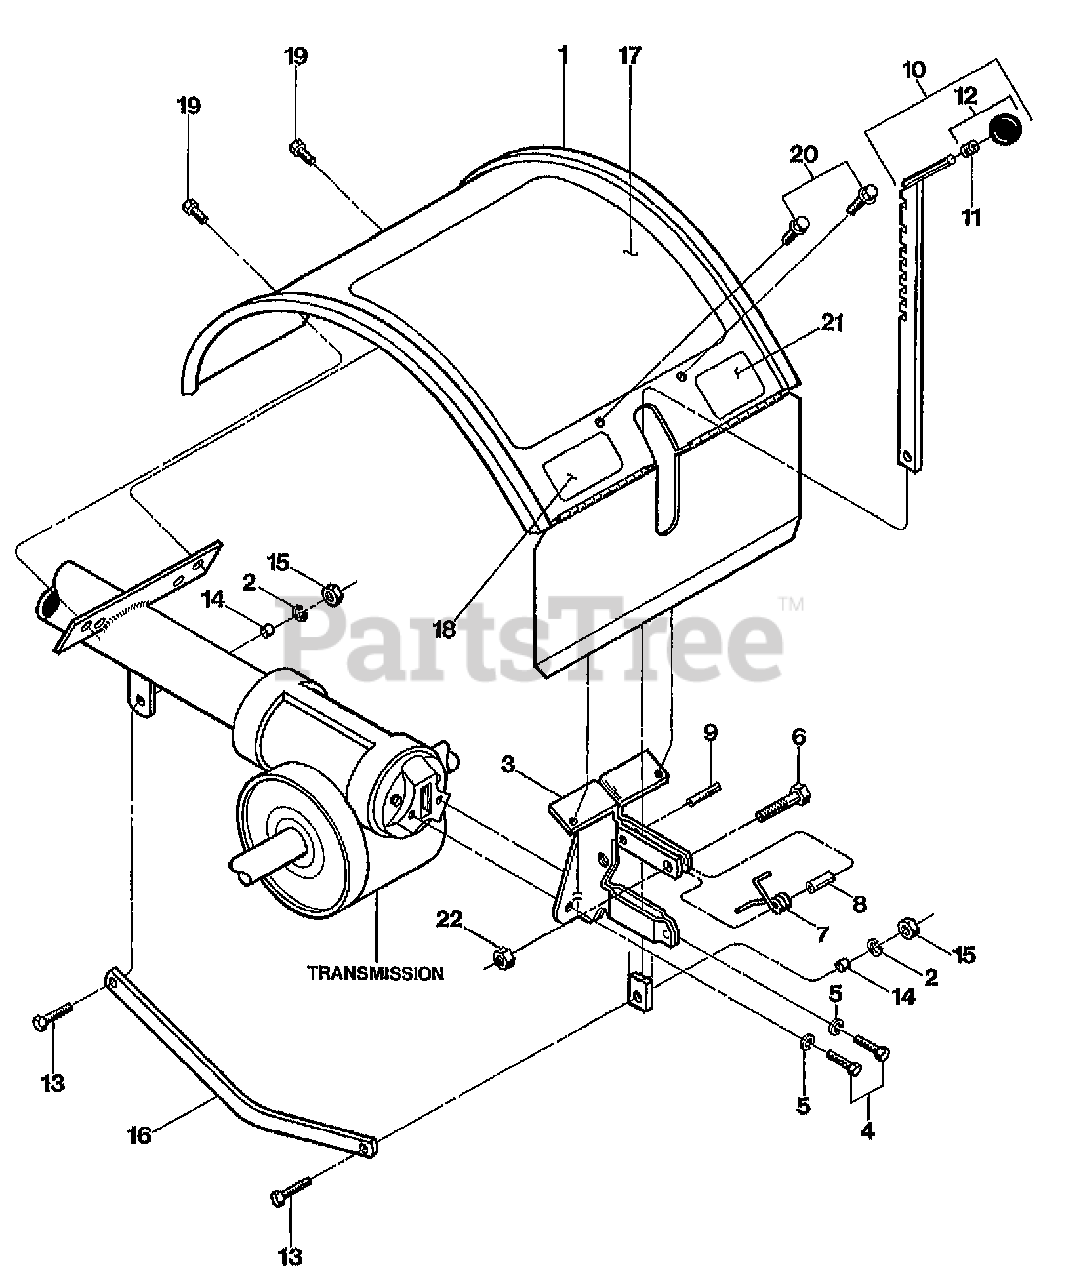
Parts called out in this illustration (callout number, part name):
1	HOOD (W/DECALS #50241, 50250 & 20814)
2	WASHER-LK .375 @ DEPL
3	BRKT W/ROLL PIN (9308)
4	SCR-HHC 5/16-18X.75 (BRKT TO REAR BEAR CAP)
5	WASHER-LK .312 ZP
6	SCR-HH 1/4-20X1.0
7	SPRING-TORSION
8	SPACER-.250X.343X.375
9	PIN-ROLL .25 X 1 (SPIRAL)
10	DEPTH REGULATOR W/KNOB (INCL. #11 & 12)
11	RING-TOLERANCE .5325 ID
12	KNOB-CONTROL (INCL. #11)
13	SCR-HH 3/8-16X1.25
14	BUSHING-.5X.375X.3
15	NUT-HEX 3/8-16 ZP
16	DRAG BAR-BENT
17	DECAL-HOOD INST JR OPC
18	DECAL-LOGO JUNIOR OPC
19	SCR-HWH 5/16-18 X .5 STH
20	SCR-HWH 1/4-20 X .5 STH
21	DECAL-TINE WARN SM FRAME
22	NUT-LK 1/4-20
